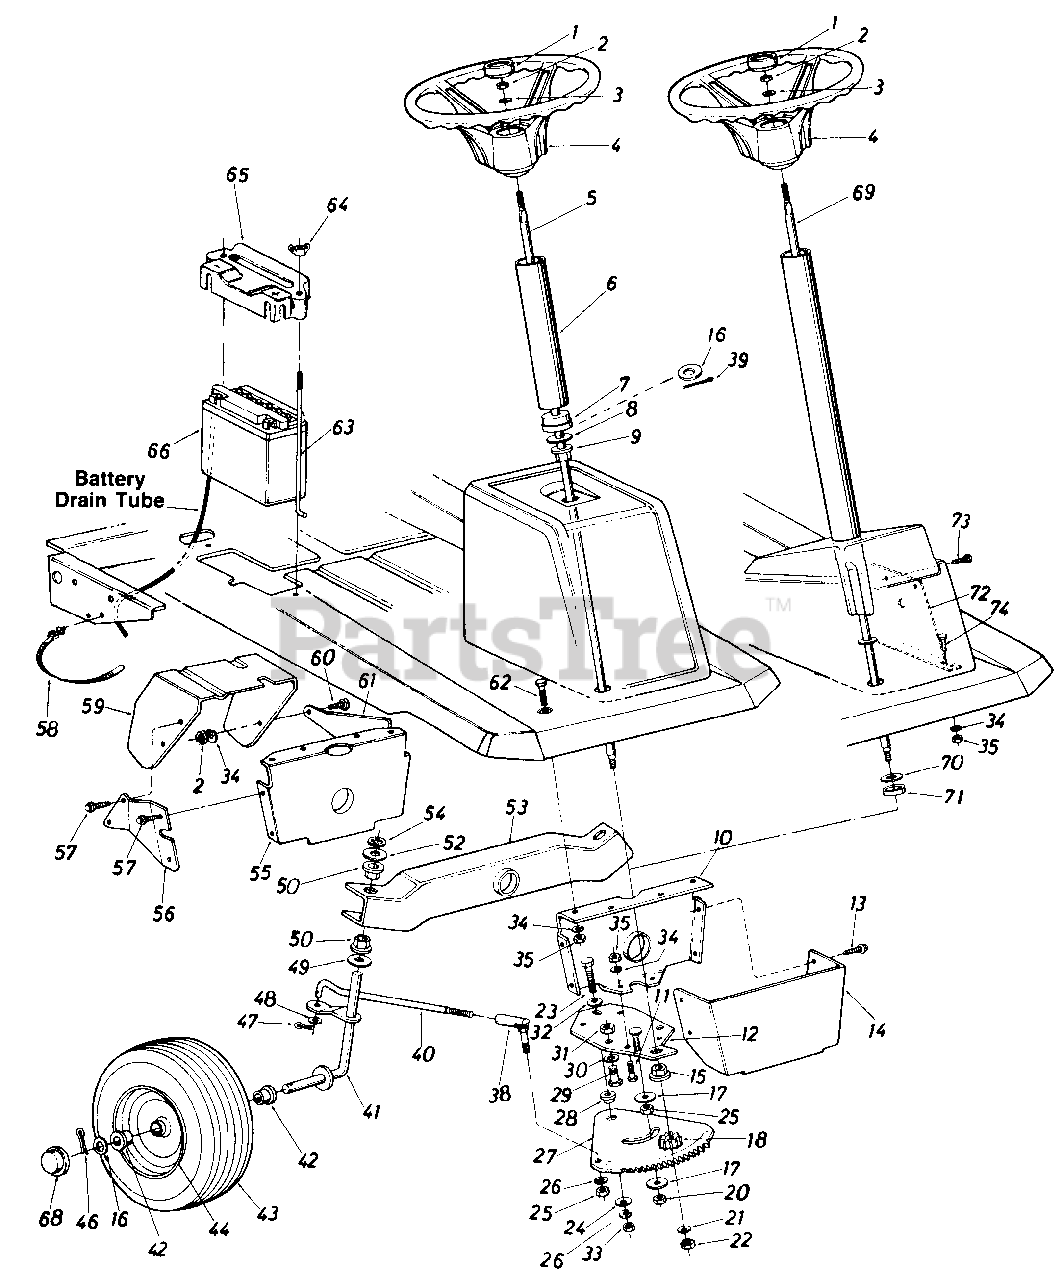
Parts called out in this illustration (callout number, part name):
1	Steering Wheel Cap
2	Hex L-Nut 5/16-24 Thd.
3	Bell-Wash. .345" I.D. x .88"
4	Steering Wheel Ass'y.
5	Steering Shaft
8	Fl-Wash. .635" I.D. x 1.24"
9	Hex Flange Bearing
10	Pivot Bar Bracket
11	Hex Bolt 5/16-18 x .75" Lg.
12	Steering Gear Support Brkt.
13	Hex Wash. Hd. AB-Tap Scr. 1/4 X .62" Lg .
16	Fl-Wash. .640" I.D. x 1.5"
17	Fl-Washer 3/8" I.D. x 1.37"
18	Steering Pinion Gear
20	Hex L-Nut 3/8-24
21	Fl-Wash. .34" I.D. x .68"
22	Hex Nut 5/16-24 Thd.
23	Hex Bolt 3/8-24 x 1.25" Lg. (Grade 5)
24	Fl-Wash. .385" I.D. x 1.38"
25	Hex Nut 3/8-24 Thd.
26	L-Wash. 3/8" I.D.
27	Steering Gear Segment
28	Shoulder Spacer .622" Dia.
29	Hex Bolt (Nylon) 1/2-13 x .75
30	Fl-Wash. .530" I.D. x .930"
31	Hex Nut 1/2-13 Thd.
32	Bell-Wash. .385" I.D. x .88"
33	Hex Nut 3/8-24 Thd.
34	L-Wash. 5/16" I.D.
35	Hex Nut 5/16-18 Thd.
38	Ball Joint Ass'y. 3/8-24 Thd.
39	Cotter Pin 1/8" Dia. x 1.0"
40	Steering Tie Rod
41	Front Axle Ass'y. R.H.
42	Flange Bearing .632" I.D.
43	Wheel Ass'y. Comp. (11 x 4.0)
44	Rim Only (11 x 4.0)
46	Cotter Pin 1/8" Dia. x 1.25"
47	Cotter Pin 1/8" Dia. x 1.00"
48	Fl-Wash. .385" I.D. x .87"
49	Fl-Wash. .635" I.D. x 1.24"
50	Hex Flange Bearing
52	Fl-Wash. .635" I.D. x 1.12"
53	Pivot Bar Ass'y.
54	Speed Nut 5/8" I.D.
55	Pivot Bar Bracket
56	Bracket Reinforcement R.H.
57	Hex Wash. Hd. AB-Tap Scr. 1/4 x.62" Lg.
58	Cable Tie
59	Clutch-Brake Pedal Ass'y.
60	Hex Bolt 5/16-18 x .75" Lg.
61	Bracket Reinforcement L.H.
62	Hex Bolt 5/16-18 x .75" Lg.
63	Battery Hold Down Rod
64	Wing Nut Solid 1/4-20 Thd.
65	Battery Hold Down Cover
66	12V Battery
68	Plastic Hub Cap
69	Steering Shaft Ass'y
70	Fl-Wash. .635" I.D. x 1 24"
71	Spacer (Plastic)
74	Hex Bolt 5/16-18 x 2.00" Lg.
